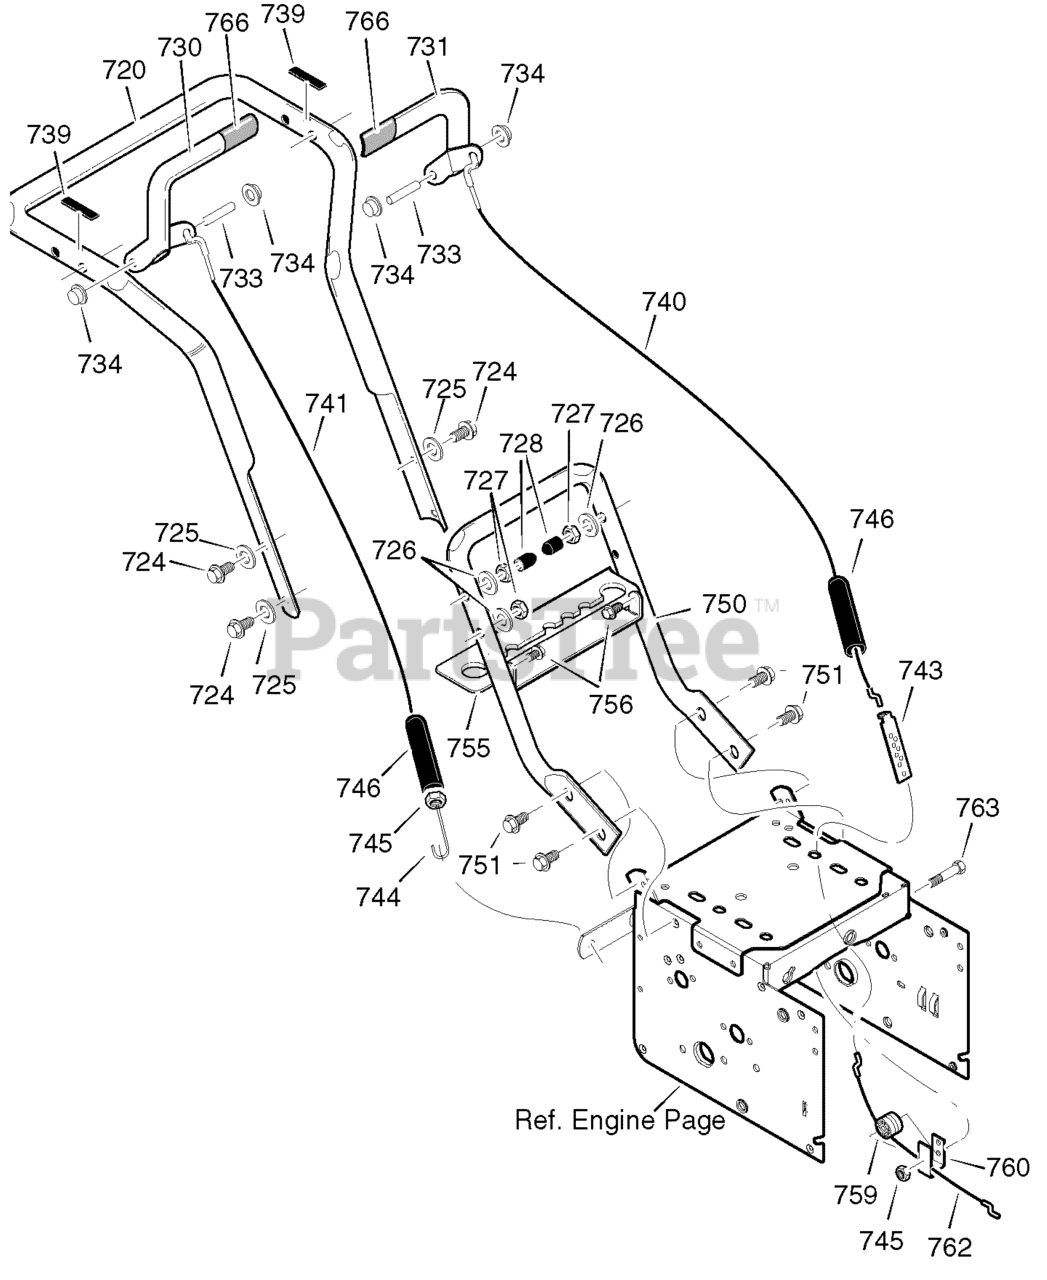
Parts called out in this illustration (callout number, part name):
720	HANDLE, UPPER
724	SCREW, 5/16-18 x 2.75
725	WASHER, FLAT
726	WASHER, SPTLK .31X.58X.08
727	NUT, 5/16-18 REGHEX
728	STOP, RED PLASTIC
730	CLUTCH HANDLE, RIGHT
731	CLUTCH HANDLE, LEFT
733	PIN, PIVOT CLUTCH
734	NUT, PUSH ON CAP
739	BUMPER, RECTANGLE
740	CABLE, CLUTCH 28.44L
741	CABLE, AUGER CLUTCH
743	BRACKET, CABLE ADJUSTER
744	SPRING, AUGER CLUTCH
745	NUT, 1/4-20
746	BOOT, CLUTCH SPRING
750	HANDLE, LOWER
751	SCREW, TAP 5/16-18 X .75
755	BRKT, GEAR SELECTOR
756	SCREW, 1/4-20 X 0.63
759	SPOOL-CABLE, AUGRT CLUTCH
760	BRACKET, CABLE SPOOL YZ
762	CABLE, LOWER DRIVE 12"
763	BOLT, HEX 1/4-20 X 1.50
